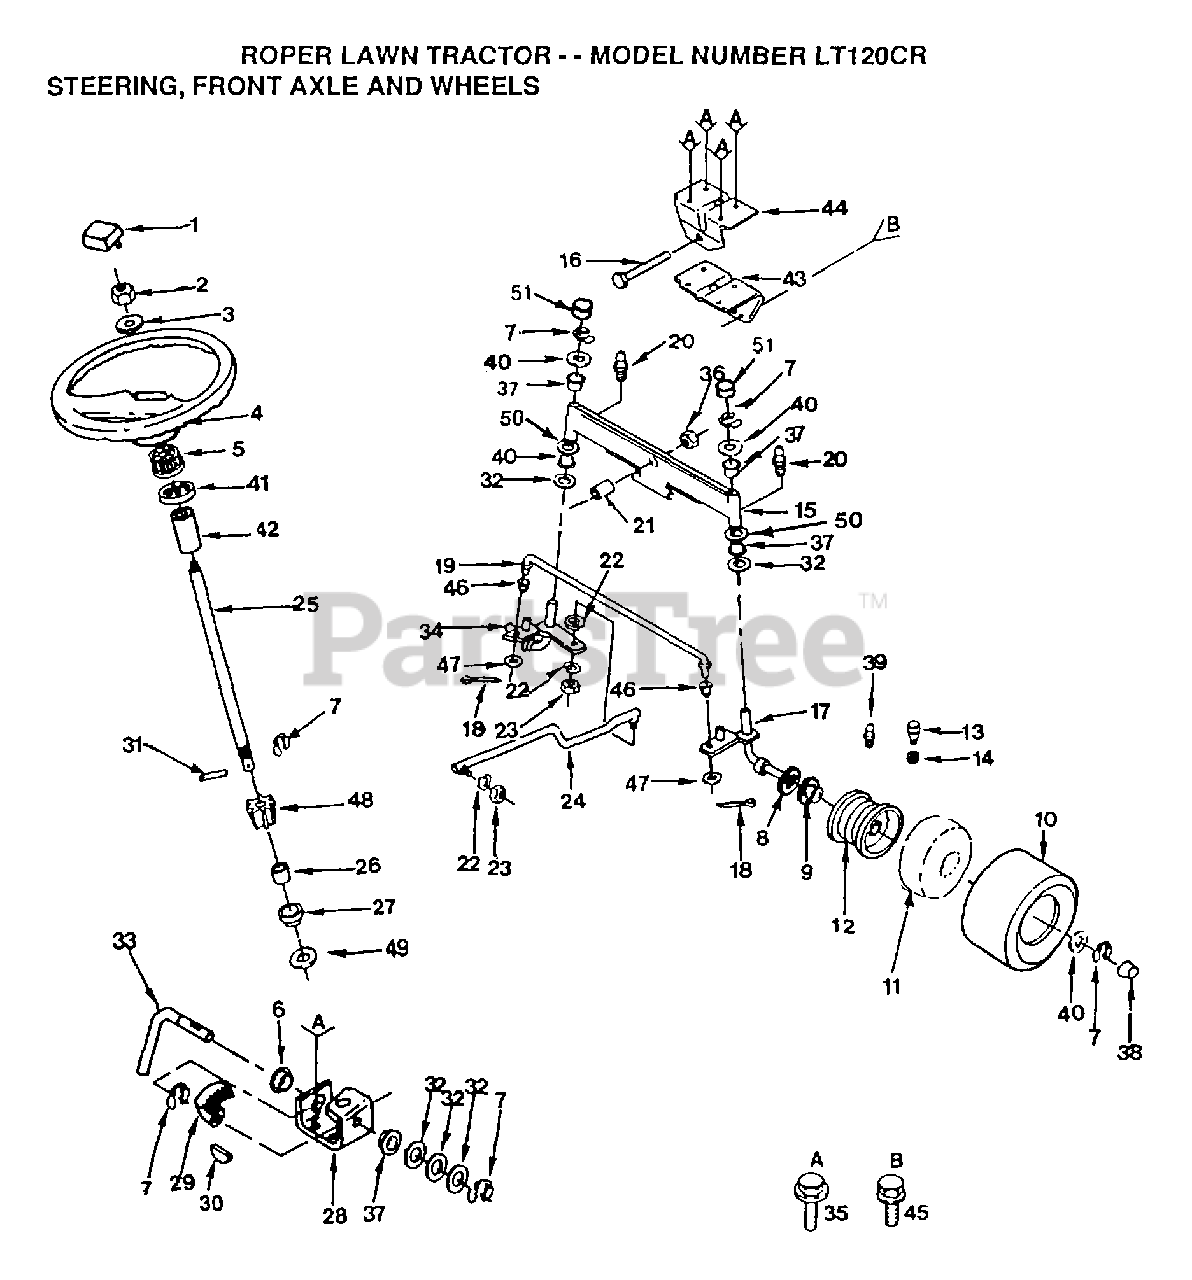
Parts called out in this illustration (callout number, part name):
1	INSERT STEERING
3	WASHER
6	NYLINER T
7	RING
8	WASHER
9	"FLANGE, BEARING"
11	TUBE.5.3/4.5/6
13	VALVE STEM LT
14	VALVE CAP
16	BOLT LT
18	COTTER PIN
20	ZERK M
21	BEARING
22	LOCKWASHER
24	LINK-DRAG LT
26	SHAFT SPACER LT
27	BUSHING
29	GEAR.SECTOR.HYT
30	KEY-WOODRUFF LT
32	WASHER .T
33	ROD STEERING T
34	SPINDLE-LH LT
35	SCREW
36	"NUT-LOC,FLANGE LT"
37	COL. SRTG. BEAR.
38	HUB CAP
39	FITTING LT
40	WASHER
43	SUPPORT.SADDLE.FT
44	SUPPORT-SADDL T
45	SCREW LT
47	WASHER
48	GEAR PINION T
50	WASHER
51	CAP
